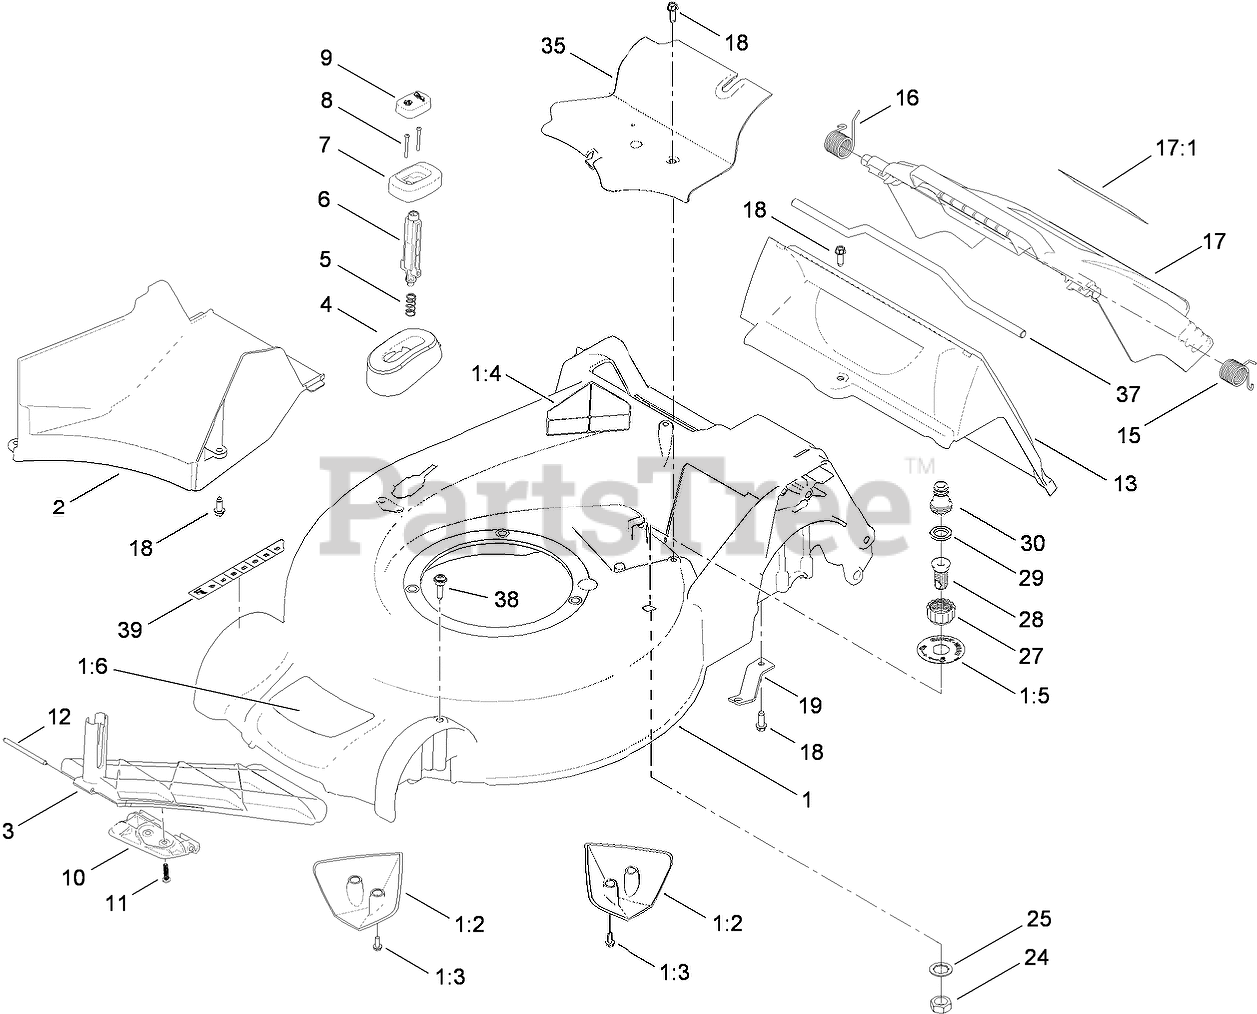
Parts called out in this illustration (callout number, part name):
1	HOUSING ASM
1:2	KICKER-FRONT
1:3	SCREW-TAPTITE
1:4	DECAL-DANGER
1:5	DECAL-PORT, WASHOUT
1:6	DECAL-HOUSING
2	RAMP-DISCHARGE
3	DOOR-RECYCLE
4	COVER-DOOR, RECYCLE
5	SPRING-COMPRESSION
6	LATCH-RECYCLE
7	HOUSING-KNOB
8	SCREW-TORX, PAN HEAD
9	KNOB-RECYCLE
10	HINGE-DOOR, RECYCLE
11	SCREW-PLASTITE
12	PIN-HINGE
15	SPRING-TORSION
16	SPRING-TORSION
17	REAR DOOR ASM
17:1	DECAL-WARNING
18	SCREW-HWHTF
19	BRACKET-CABLE, TRACTION
24	NUT-JAM
25	WASHER-TOOTH, INTERNAL
27	COUPLING-HOSE, WASHOUT PORT
28	PORT-WASHOUT
29	WASHER-SEAL, WASHOUT PORT
30	ADAPTER-CONNECT, QUICK
35	COVER-BELT
37	ROD-DEFLECTOR
38	SCREW-SHOULDER, BHTF
39	DECAL-HOC
